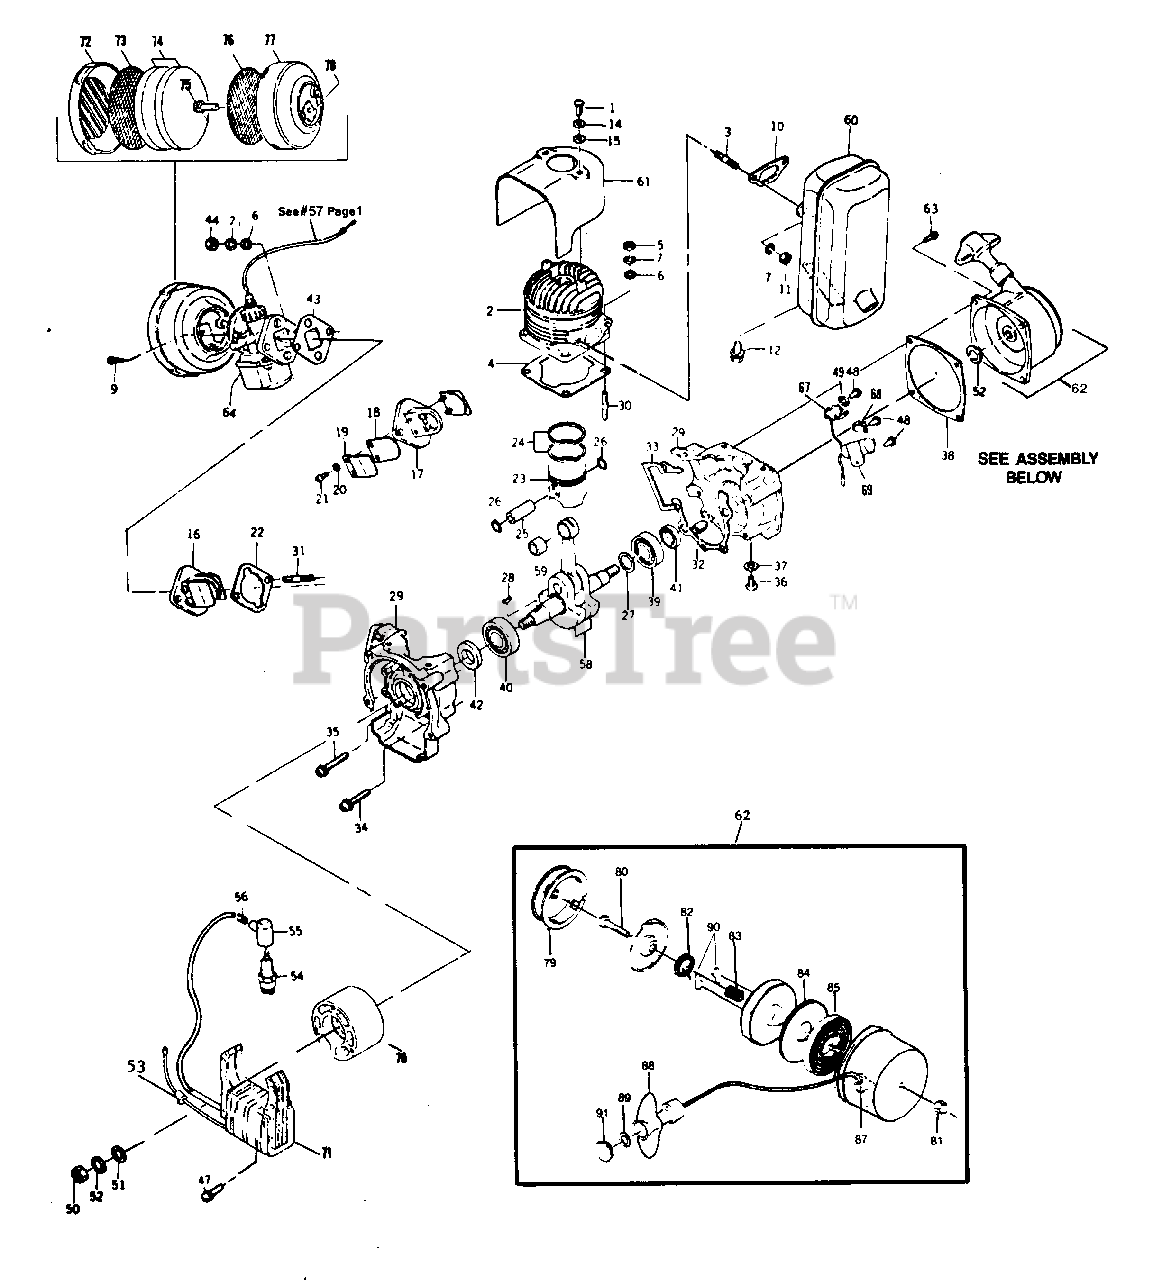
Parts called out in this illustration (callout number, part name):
1	Screw, Pan-WS + -
2	Cylinder
3	Stud-Bolt
4	Gasket, Cylinder
6	Washer-Plain-Small
7	Lock Washer
9	Screw, Pan
12	Bolt-Upset-WSP
15	Lock Washer
16	Reed Valve Assembly
17	Reed Valve Block
18	Valve, Reed
20	Lock Washer
21	Screw, Pan
24	Piston Ring Set
25	Pin, Piston
26	Ring, Snap
29	Crankcase Assembly
32	Pin, Dowel
34	Screw, Pan-WSP + -
36	Screw, Pan
39	Bearing, Ball
40	Bearing, Ball
41	Seal, Oil
42	Seal, Oil
47	Screw, Pan-WS + -
48	Screw, Pan-WS + - Lock & Plain
52	Lock Washer
54	Plug, Spark
55	Cap, Plug
56	Spring, Cap
58	Crankshaft Assembly
60	Muffler Assembly
61	Cover, Cylinder
62	Recoil Starter Assembly
63	Screw, Pan-WS + -
64	Carburetor Assembly
68	Felt, Cam
69	Condenser
71	Coil, Ignition
72	Cap, Air Cleaner
75	Screw - Pan-WS-Lock & Plain Washer
77	Case, Air Cleaner
82	Ratchet Spring
83	Spring, Return
85	Spring, Spiral
87	Guide, Rope
91	Cap, Handle
